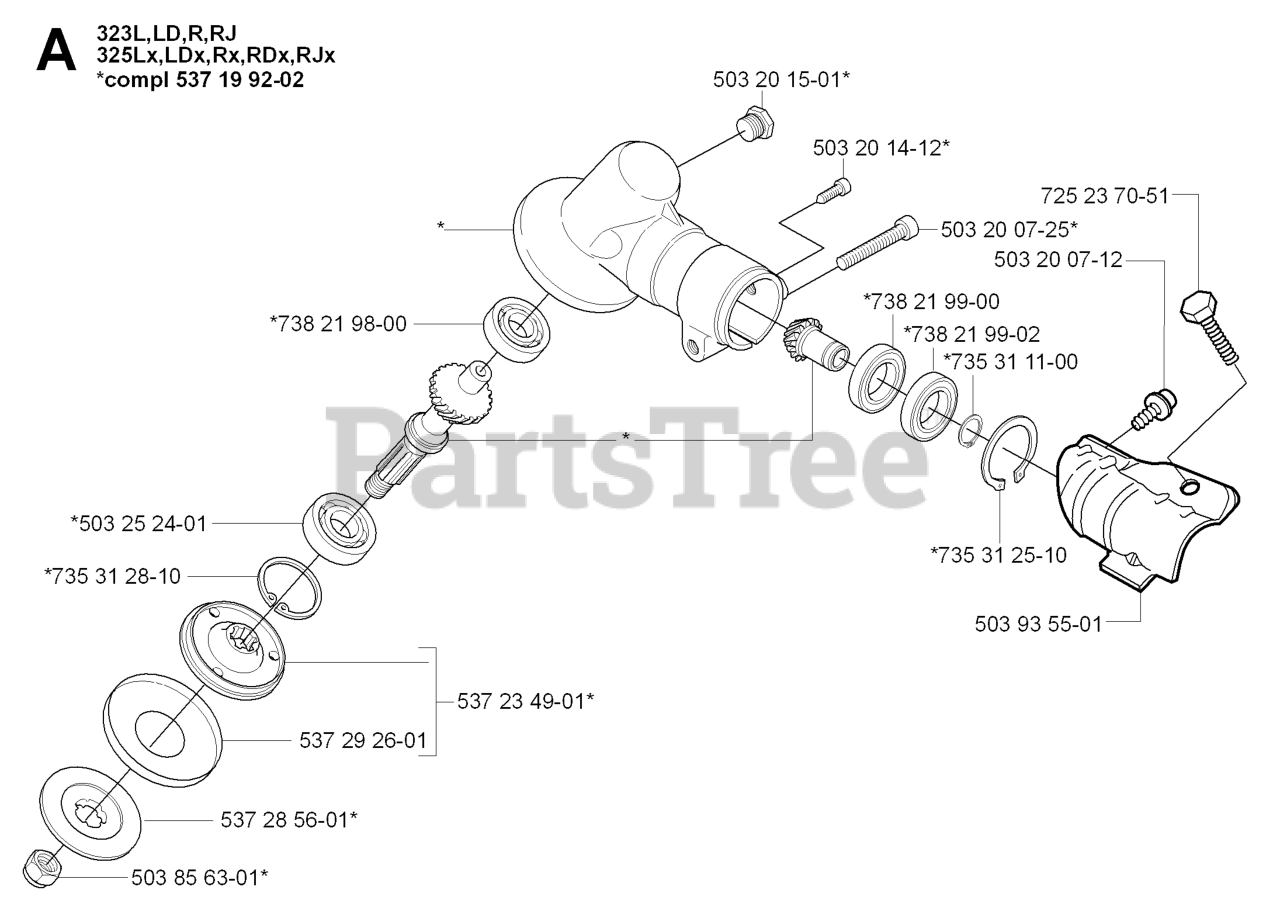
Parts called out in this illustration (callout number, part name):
1	MUFFLER NA
2	ENGINE SHEAVE
3	ELECTRIC CLUTCH
4	RESTRAINT KIT
5	JACKSHAFT MOUNT WELDMENT
6	HEAT SHIELD
7	MOUNTING BRACKET
8	AIR FILTER HOSE
9	ENGINE MOUNT-LT
10	ENGINE MOUNT-RT
11	ARM WELDMENT
14	NUT M8-1.25 STOVER
15	SPINDLE WASHER
18	BELT, PRIMARY BZ
19	ENGINE, BELT MULE
20	AIR FILTER ASSY - NON-TURBO
22	WASHER, HEAVY
23	BUSH 1-1/8 X 10 GA ZD
24	GREASE ZERK LONG
25	WASHER 3/8 SAE FLAT
26	WASHER 1/2 FLAT
27	HCS 5/16C X 3/4
28	BOLT 7/16F X 2 1/2
29	HCS 1/2C X 2 3/4
30	HTB M8-1.125 X 25MM
31	HCS 1/2C X 1 1/4 SERRATED HEAD
32	HEX SCREW 1/2-13 X 2.5" GR 5
33	HCS 5/16C X 1
35	HCS 3/8-16 X 3-1/2 GR5 ZD
36	NUT 5/16 NYLOC
37	NUT 3/8-16 NYLOC
38	NUT 1/2-13 HEX NYLOC ZD
39	WASHER 7/16 LOCK
40	WASHER.LOCK.HVY.HLCL.SPR.5/16
41	KEY 1/4 SQ X 2-1/2
42	WASHER 5/16 FLAT
43	HCS 7/16F X 1 1/2
44	COMBO SPACER
45	HOUSING, DIE CAST
46	BEARING
48	SPINDLE WASHER
51	KEY 1/4 SQ X 1 1/8
52	BUSHING.MACHINE.18.GAUGE
55	AIR FILTER
56	SAFETY ELEMENT
57	BODY - 90 DEG
58	PRECLEANER ASM
59	MOUNTING BRACKET
63	NUT 5/16C WHIZ
64	HCS 5/16C X 1 1/4
539106327	STUB SHAFT
539109177	MANIFOLD GASKET
